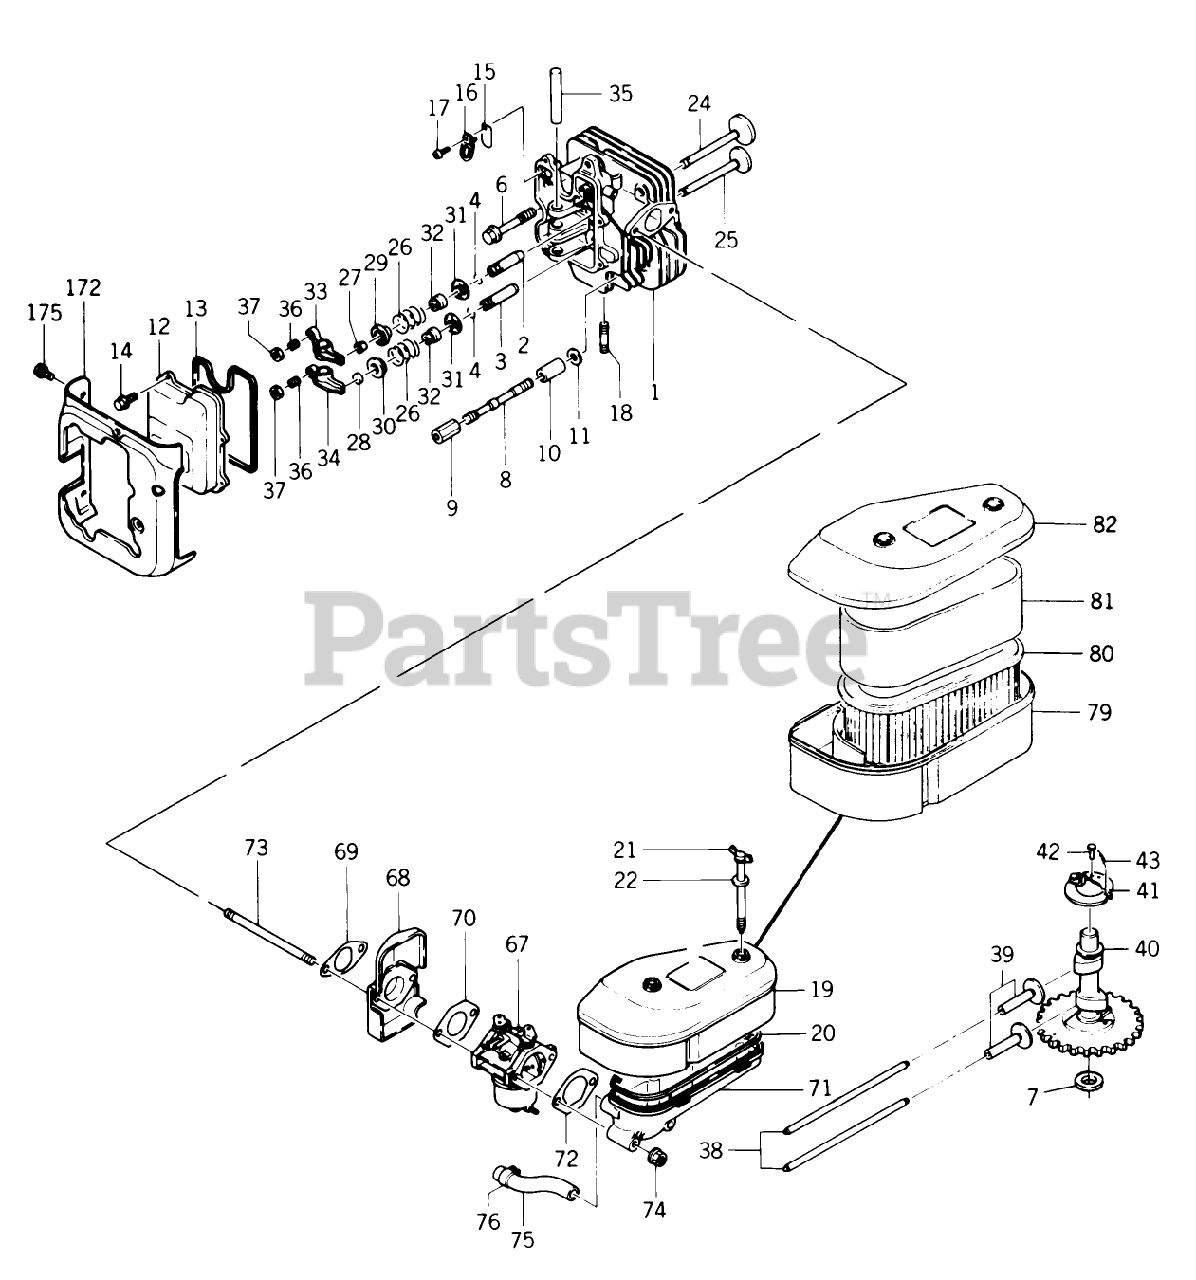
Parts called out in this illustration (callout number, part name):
19	Air Filter Assembly
26	ORDER KAWASAKI#49078-2061
70	GASKET
81	WRAPPER AIR FILTER
